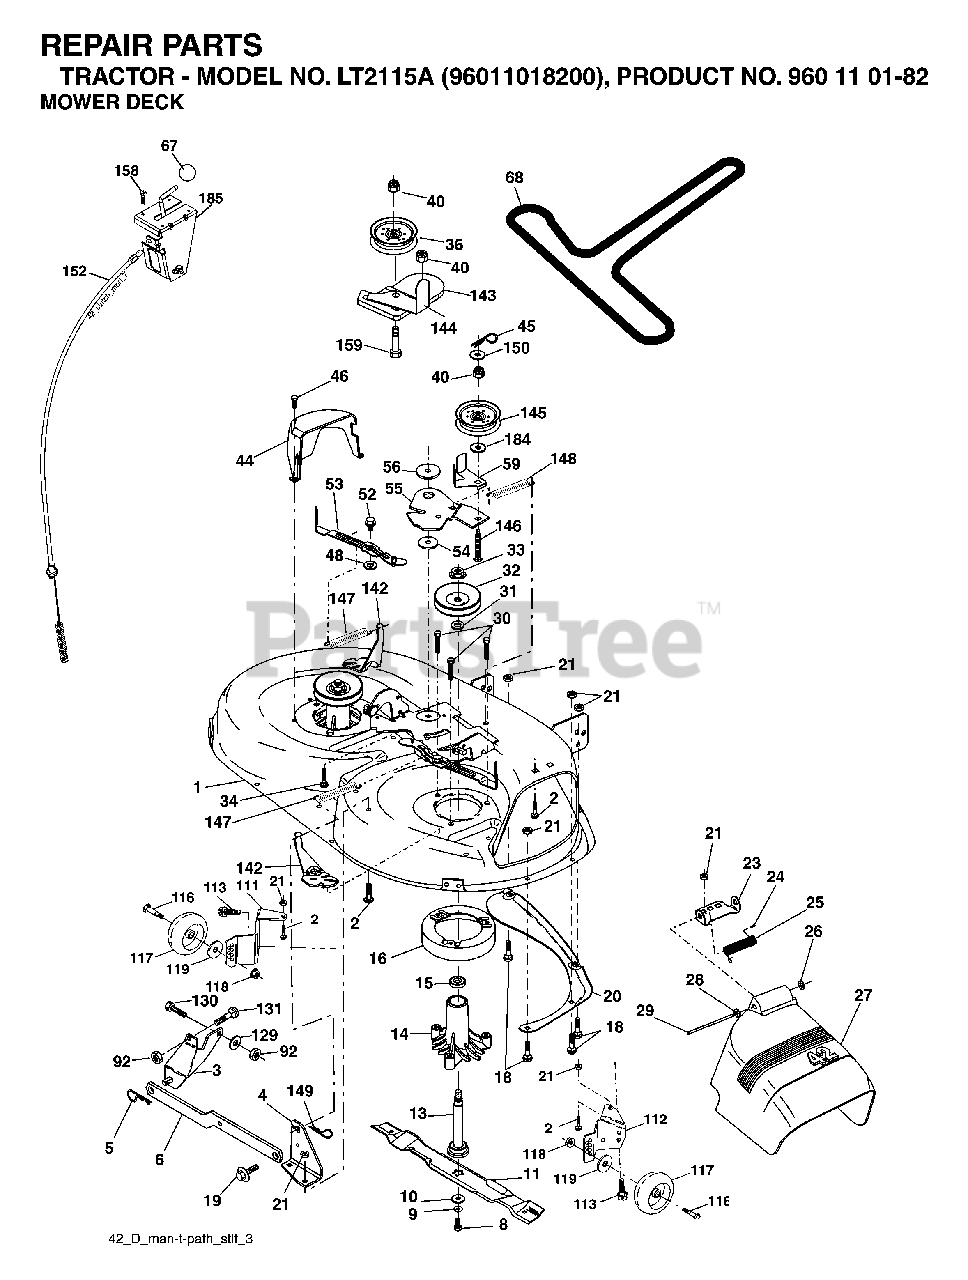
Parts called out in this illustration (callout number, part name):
1	42" DECK KIT
2	BOLT
3	BRKT ASM SWAY BAR
4	BRACKET SWAY BAR 42" DECK
5	RETAINER-SPRNG RB
6	BAR SWAY DECK
8	BLADE BOLT
9	LOCKWASHER
10	WASHER.BLADE
11	BLADE.42".MULCH
13	SHAFT ASM VENT
14	HSG MANDREL
16	STRIPPER, MWR ROUND
18	BOLT
19	BOLT SHD 5/16-18
20	BAFFLE.VORTEX
21	LOCKNUT
23	BRKT, DEFL. MOWER
24	CAP-SLEEVE LT
25	SPRING TORSION
26	NUT PUSH M
27	SHIELD DEFLECTOR
28	WASHER
29	ROD.HINGE
30	SCREW, WASHER HEAD
31	WASHER.SPACER.MANDREL
32	PULLEY/MANDREL
33	NUT.FLANGE.LOCK.TOP
34	BOLT.3/8-16X1.50
36	FLAT IDLER PULLEY
40	NUT LOCK FLG 3/8-16 UNC
44	GUARD MANDREL LH BLACK
45	RETAINER M
46	SCREW.1/4-20X5/8
53	ARM BRAKE ASSY
55	ARM IDLER 42" MOWER LT/YT
56	SPACER.RETAINER.MOWER
59	GUARD, BELT
67	KNOB T (3/8 HOLE)
92	NUT
111	BRACKET, WHEEL
112	BRACKET, WHEEL
113	BOLT.5/16HEX.WHS.HD
117	WHEEL.GAGE.HALF.SPOKED
118	LOCKNUT
119	WASHER
129	WASHER
131	BOLT D
142	ARM SPRING BRAKE MOWER
143	BRACKET, ARM IDLER
144	KEEPER.BELT.42".CLUTCH.CABLE
145	PULLEY
146	BOLT, CARRIAGE IDLER BLACK
148	IDLER RETURN SPRING
149	SPRING.RETAINER.YELLOW.ZINC
150	WASHER LT
152	42" CLUTCH CABLE
158	SCREW
159	BOLT
184	WASHER
185	HEAD ASM. CABLE CLUTCH
